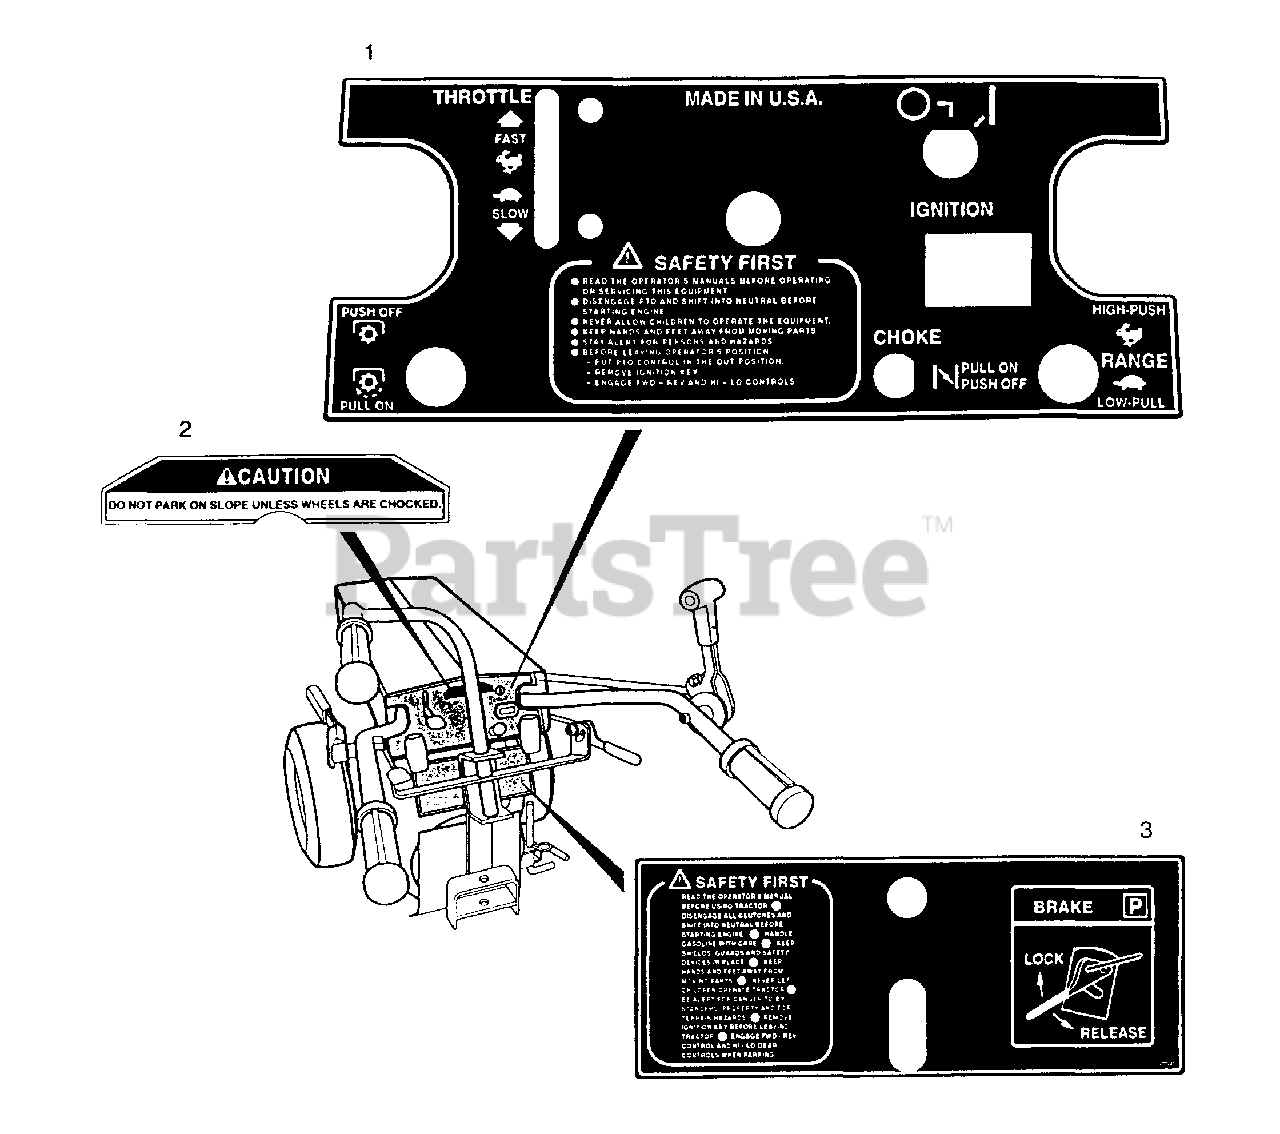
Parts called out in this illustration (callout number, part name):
1	Decal, Instr Panel, 2 Wheel Tractor
2	Decal, CAUTION
3	Decal, 2 Wheel Instructions
